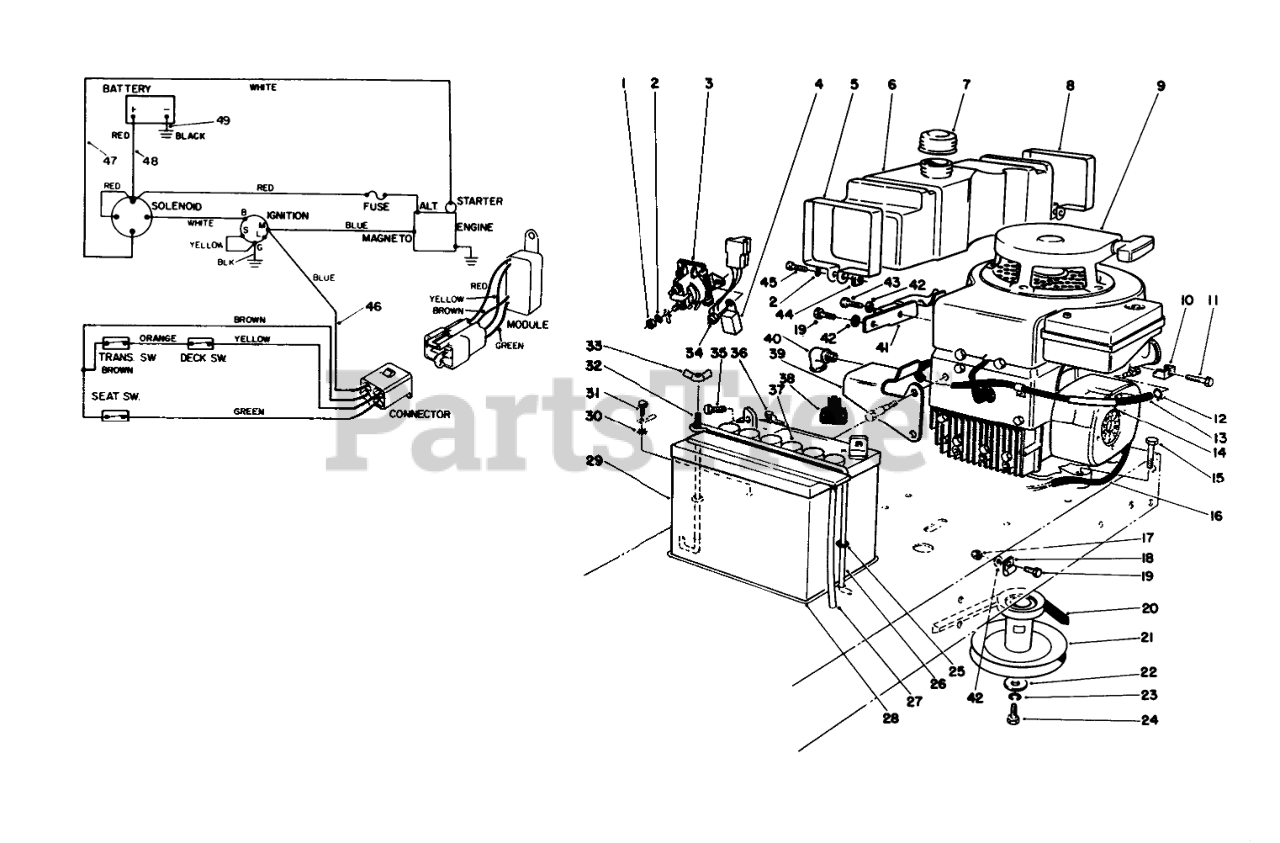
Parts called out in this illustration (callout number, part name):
1	NUT-JAM
2	WASHER-LOCK
3	SOLENOID
4	INTERLOCK MODULE
5	Retainer-Front
6	TANK-5 QT GAS
7	GAS CAP ASM
8	Retainer-Tank Rear
10	CLAMP-CASING
11	SCREW W ENGINE
12	CLAMP-HOSE
13	HOSE-FUEL
14	SUPPORT-FUEL LINE
15	SCREW-HH
16	HEAT SHRINK TUBING
17	NUT-LOCK, NI
18	CLAMP
19	SCREW-HH
20	V-BELT, TRACTION
21	PULLEY
22	WASHER-FLAT
23	WASHER-LOCK
24	SCREW-HH
25	O-RING
26	HOLDDOWN-BATTERY
27	TUBE-BATT DRAIN/80-2600
28	PAD-SKID, ANTI
29	Battery
30	WASHER-LOCK, INTERNAL
31	SCREW-HHF
32	POST-BATTERY
33	NUT-WING
34	NUT-LOCK, CONE
35	SCREW-HH
36	NUT-WING
37	CAP-BATTERY
38	BOOT-TERMINAL
39	FRT TANK MTG BRKT B
40	ELBOW-STREET, 90 DEG
41	Bracket-Mount Tank Rear
42	WASHER-PLAIN
43	SCREW-HH
44	NUT-SQUARE
45	SCREW-HSH
46	WIRE HARNESS
47	STARTER WIRE HARNESS
48	WIRE ASM
49	WIRE ASM(BATT/GRD.
